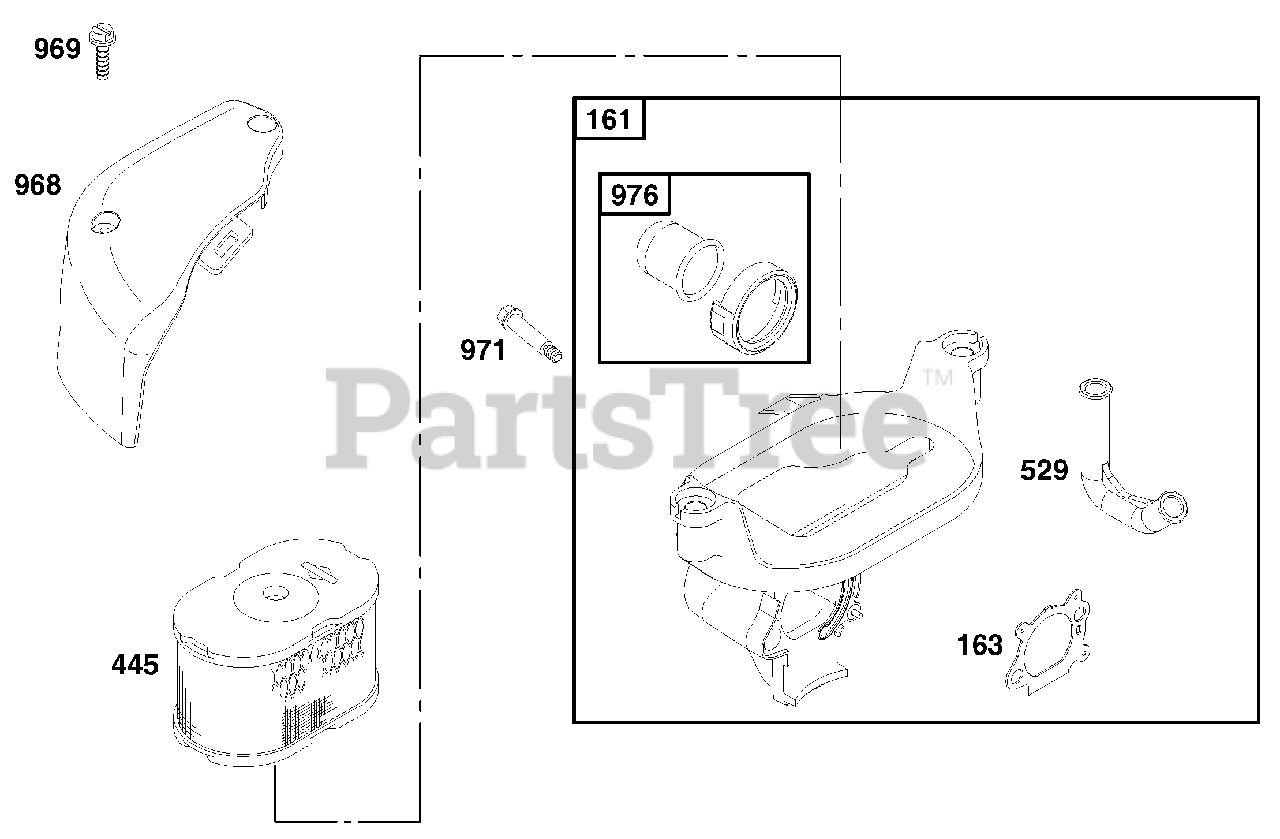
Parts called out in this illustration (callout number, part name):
161	Base-A/C Primer
163	Gasket-Air Cleaner
445	Filter-A/C Cartridge
529	Tube-Breather
968	Cover-Air Cleaner
969	Screw-Slotted Hex.
971	Screw-Shoulder
976	Primer-Carburetor
